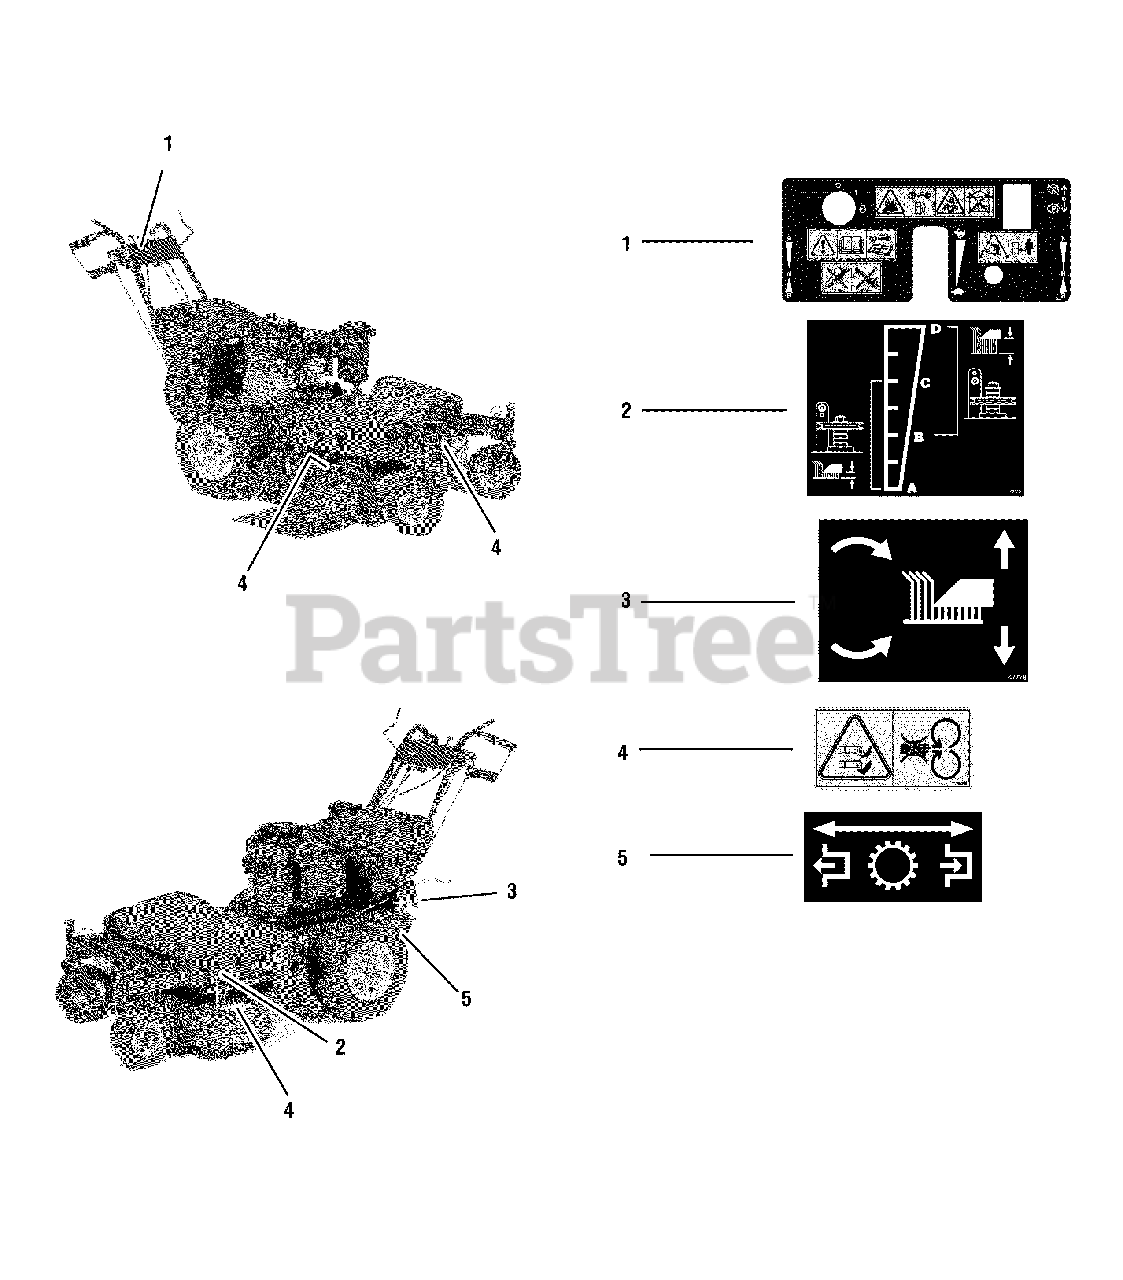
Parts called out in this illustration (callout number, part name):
1	DECAL, CONTROL PLANEL, HC
2	DECAL, HEIGHT OF CUT
3	DECAL, DECK HEIGHT ADJUST
4	DECAL, DANGER, ROTATING BLADES
5	DECAL, HYDRO RELEASE
